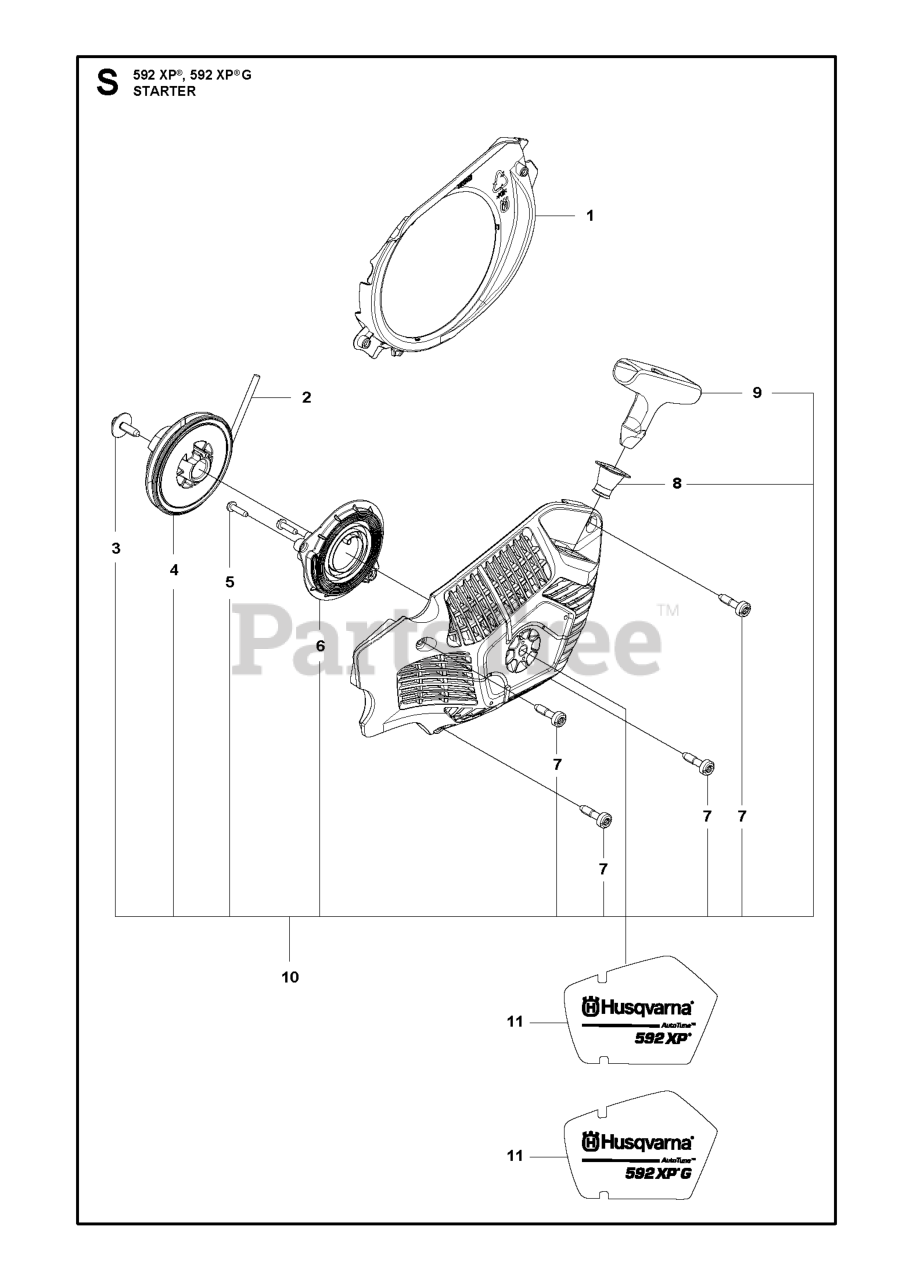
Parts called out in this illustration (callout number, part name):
1	COOLING AIR CONDUCTOR
2	STARTER CORD
3	SCREW ITXSCT MT5X16 10.9 TBO
4	STARTER PULLEY
5	SCREW CITXPANT
6	SPRING CASSETTE ASSY
7	SCREW CITXPANMO
10	STARTER ASSY KIT 90CC SPARE PA
11	LABEL STARTER HOUSING 592 XP -
11	LABEL STARTER HOUSING 592 XPG
